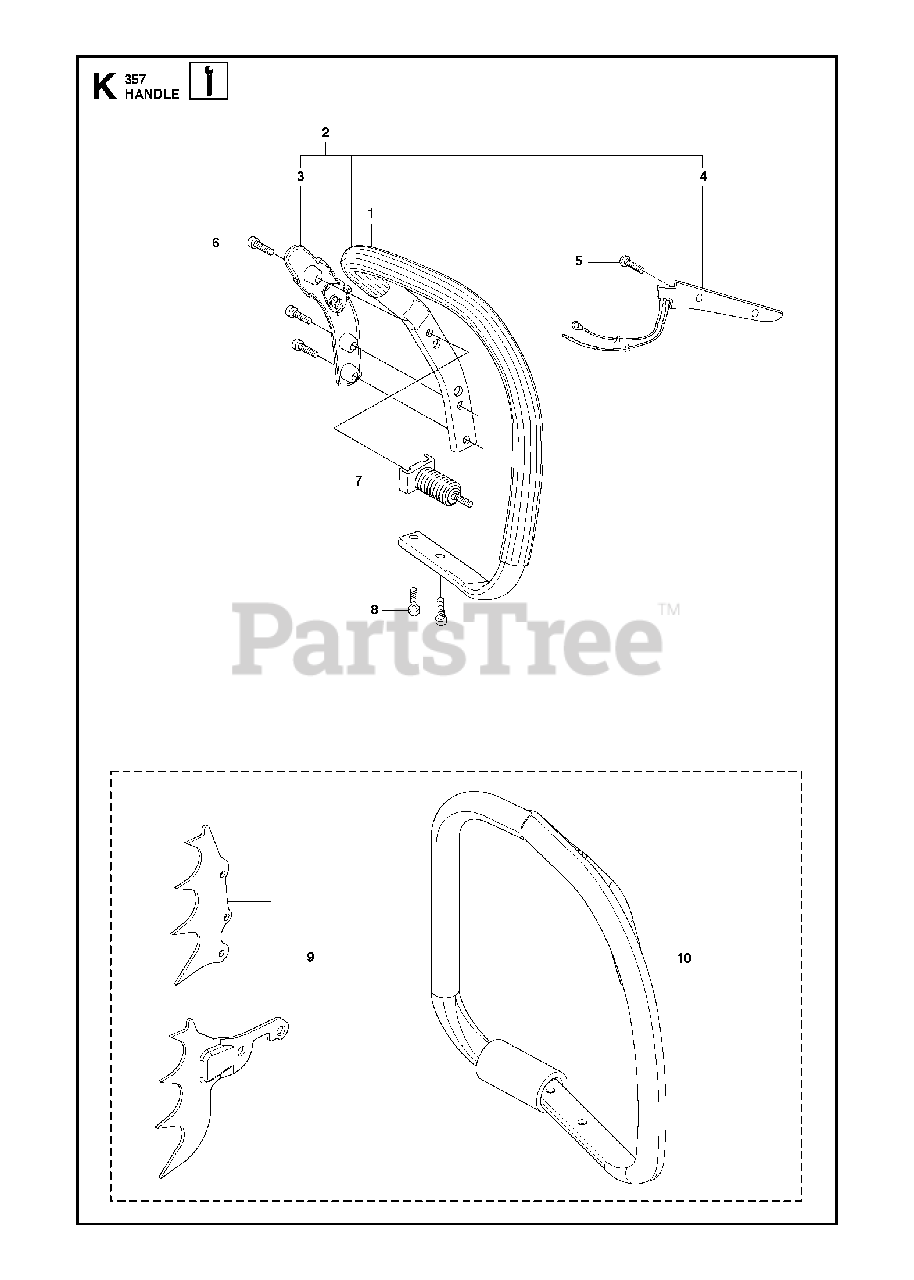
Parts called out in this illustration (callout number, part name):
1	FRONT HANDLE
2	FRONT HANDLE
3	SWITCH
4	HANDLE CIRCUIT
5	SCREW
8	SCREW IHSCFT
9	FELLING DOG
10	HANDLE-WRAP 359/357
10	HANDLE WRAP (G)
